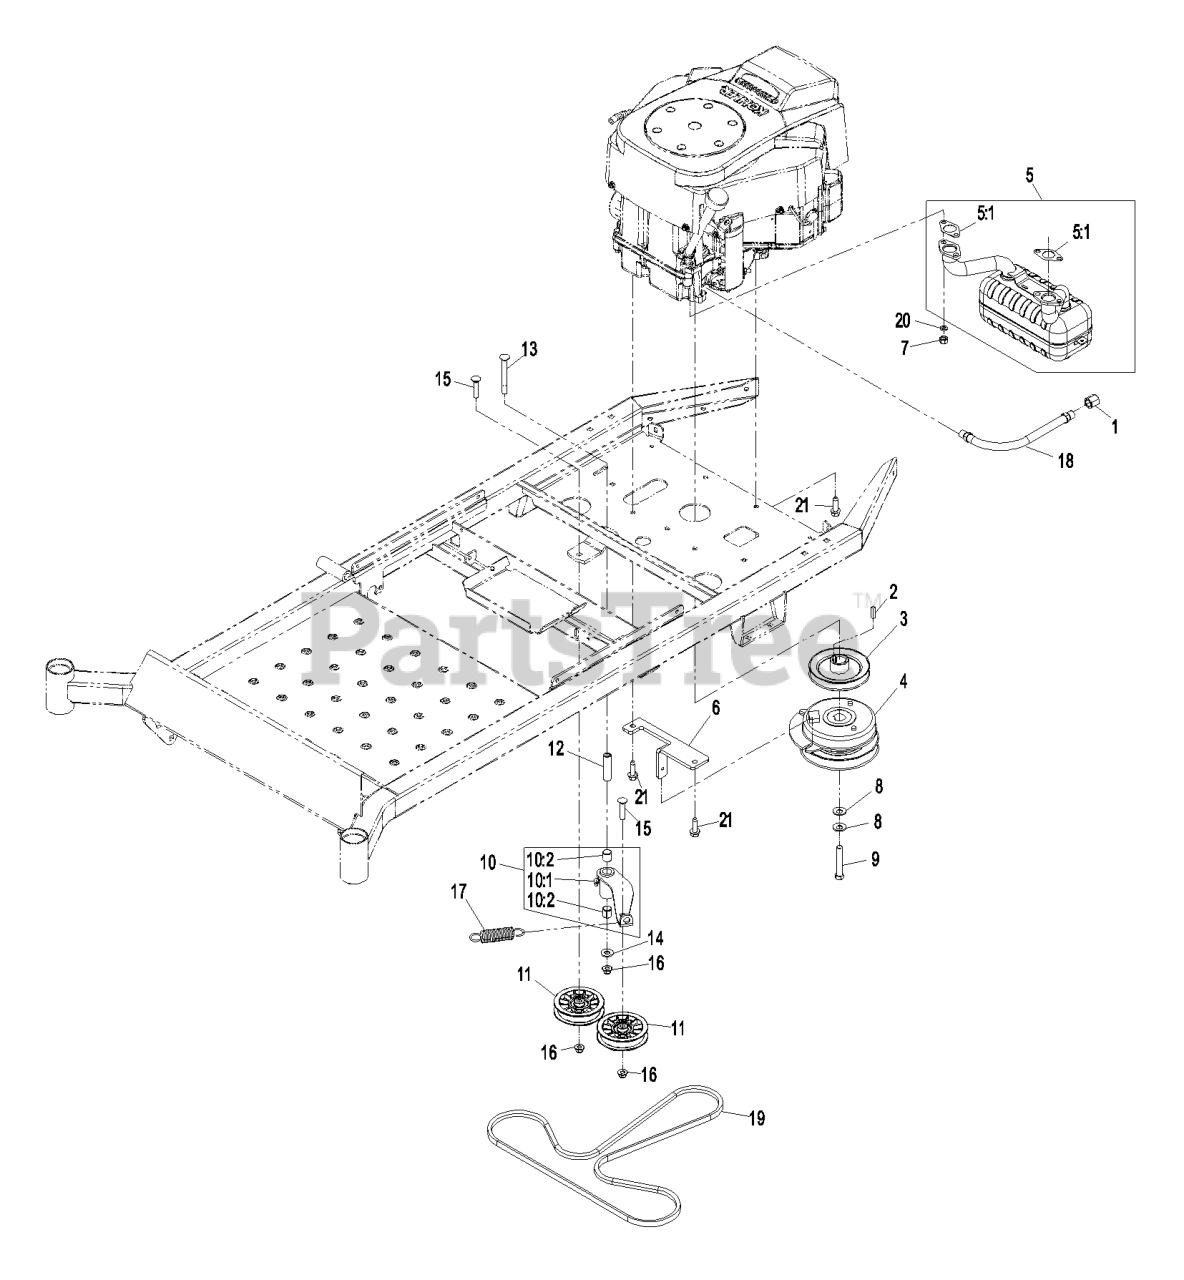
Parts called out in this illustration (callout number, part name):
1	CAP-PIPE
3	SHEAVE-SPLIT STEEL
4	CLUTCH-ELECTRIC, PTO
5	MUFFLER ASM
5:1	GASKET-EXHAUST
6	ANCHOR-CLUTCH
7	NUT-HEX
8	WASHER-SPRING
9	SCREW-HH
10	IDLER ARM ASM
10:1	FITTING-GREASE, 90 DEG
10:2	SLEEVE-BEARING
11	PULLEY-IDLER, FLAT
12	BUSHING-PIVOT, IDLER
13	SCREW-CARR
14	WASHER-FLAT
15	SCREW-CARR
16	NUT-HF, NI
17	SPRING-EXTENSION
18	HYD HOSE ASM
19	BELT
20	WASHER-LOCK
21	SCREW-THD
